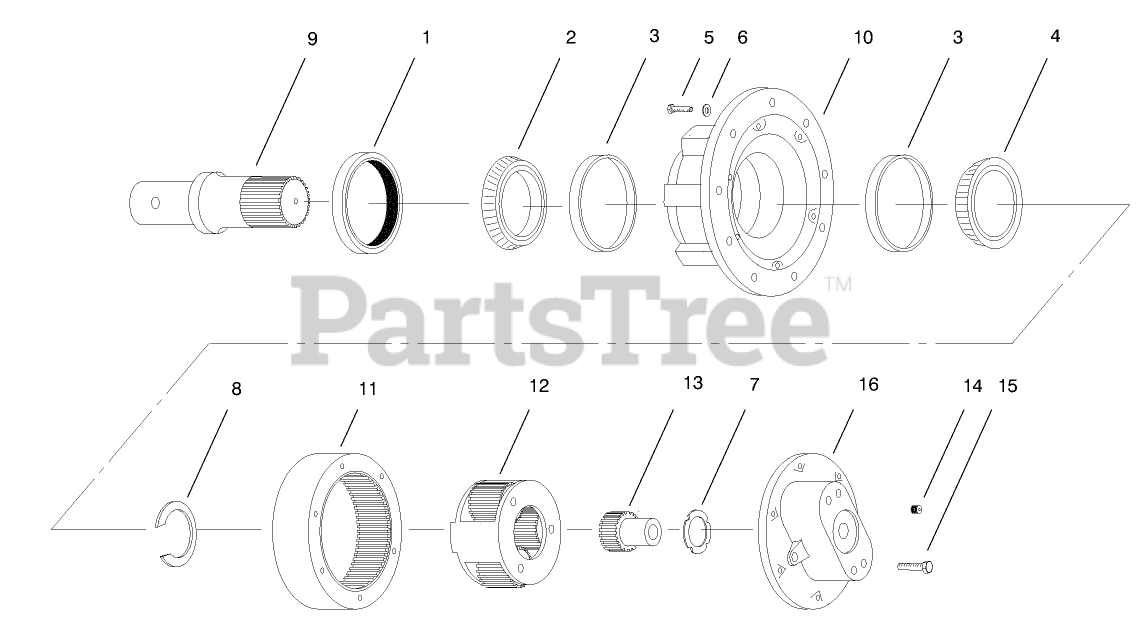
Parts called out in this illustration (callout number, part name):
6	WASHER
7	WASHER
8	RETAINING RING KIT
9	SHAFT - OUTPUT
10	HUB W/HOLES
11	GEAR - RING
12	CARRIER ASM
13	GEAR - SUN
14	PLUG - PIPE, MAGNETIC
16	COVER
